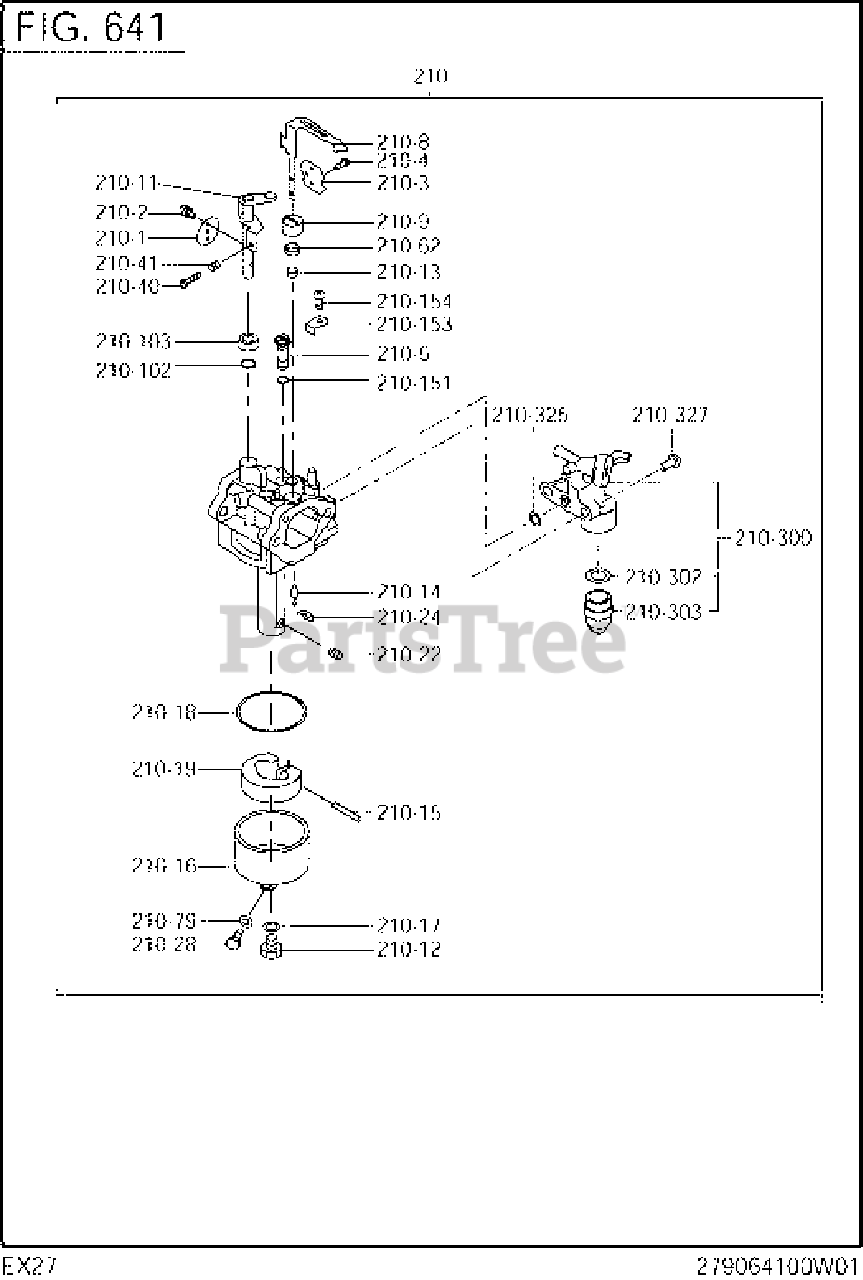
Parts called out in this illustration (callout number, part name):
210-1	THROTTLE VALVE
210-4	SCREW
210-11	THROTTLE SHAFT-A
